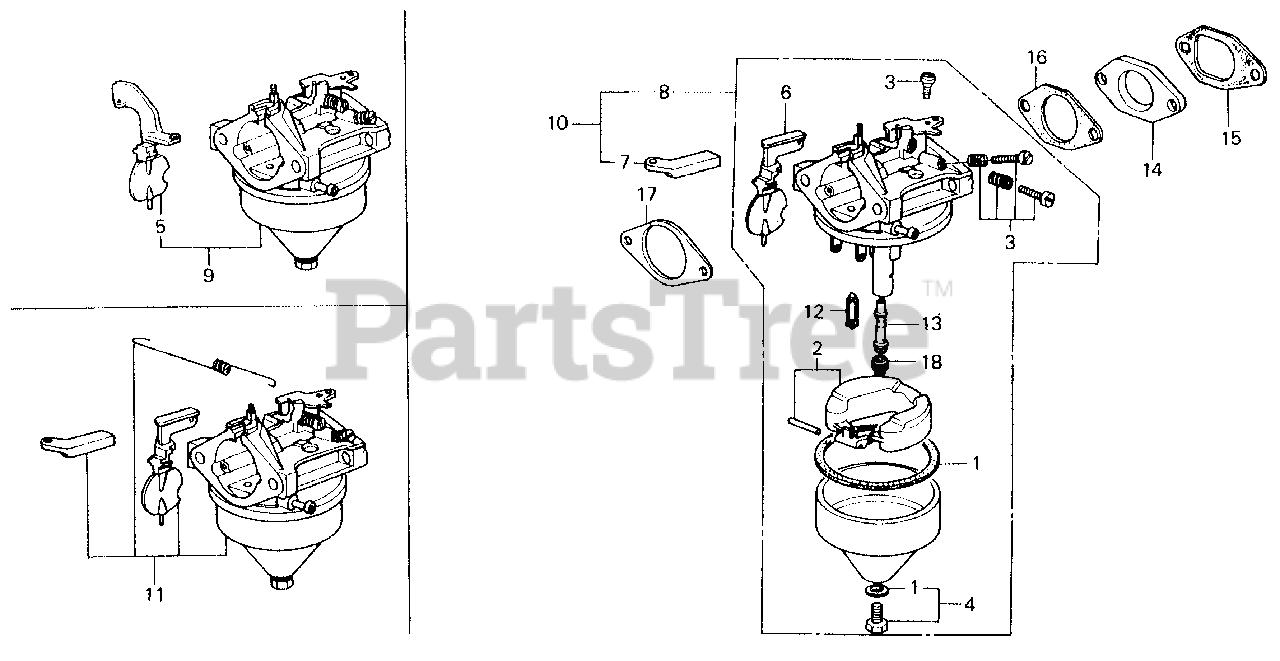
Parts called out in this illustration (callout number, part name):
1	GASKET SET
2	FLOAT SET
3	SCREW SET A
4	SCREW SET B
5	CHOKE SET (NOT AVAILABLE)
6	CHOKE SET
7	ARM, CHOKE LEVER Use from Engine SN 1222430 to 1484486.
8	CARBURETOR ASSY.
8	CARBURETOR ASSY. (BB30A D)
9	CARBURETOR ASSY.
9	CARBURETOR ASSY. (BB30A A)
10	CARBURETOR ASSY.
11	CARBURETOR ASSY.
12	VALVE, FLOAT
13	NOZZLE, MAIN
14	INSULATOR, CARBURETOR
15	GASKET, INSULATOR
16	GASKET, CARBURETOR
17	GASKET, AIR CLEANER
18	JET, MAIN (#65) Use up to Engine SN BB30A D.
18	JET, MAIN (#68) Use up to Engine SN BB30A D.
18	JET, MAIN (#70) Use up to Engine SN BB30A D.
18	JET, MAIN (#72)
